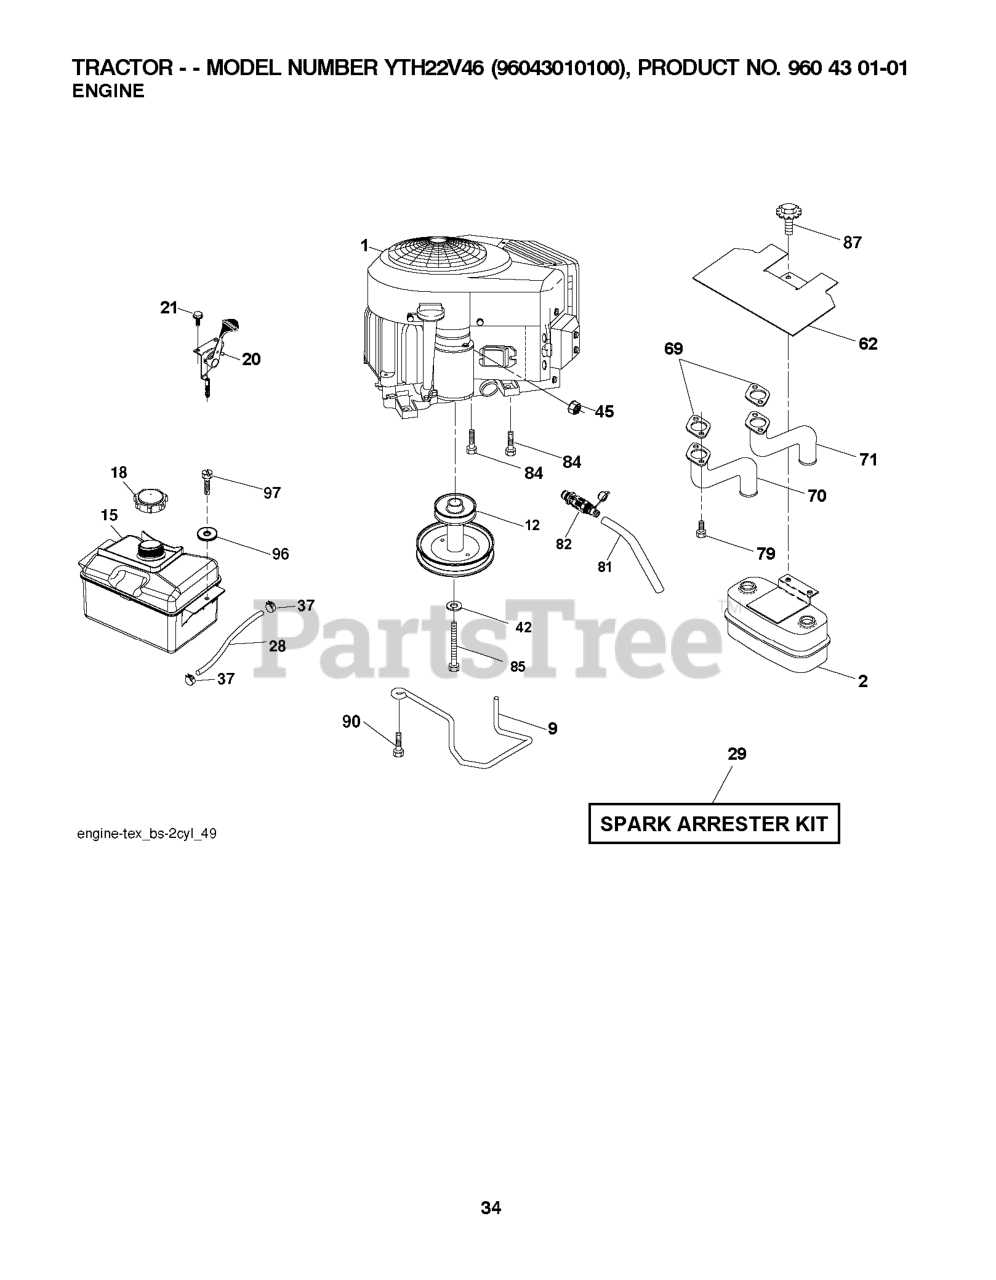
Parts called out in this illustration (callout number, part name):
2	MUFFLER.TWIN.CYL.LOW.TONE
9	KEEPER.BELT.ENGINE.4.2
12	RP_PULLEY ENGINE
15	TANK.ASM.FUEL.FR.2.5GA.
18	CAP ASM.FUEL.2.25"FR.
20	CONTROL.TH/CK.COBRA.B&S.TWN.BK
21	SCREW.#10 X 0.750.BOS
22	CONTROL.CHOKE.ERGO.PUSH-IN.BLA
28	LINE.FUEL.20"FRONT.EMI
29	KIT.SPARK ARRESTOR 794945 B&S
37	HOSE CLAMP
42	LOCKWASHER
45	NUT
62	RP SHIELD HEAT MUFFLER
69	GASKET.MUFFLER
70	RP.EXHAUST.TUBE.LH.BS/TWIN
71	EXHAUST.TUBE.RH.BS/TWIN
79	SCREW.SOCKET.HEAD.5/16-18
81	TUBE, DRAIN OIL ASM.
82	VALUE.OIL.DRAIN
84	SCREW.3/8-16
85	BOLT HEX 7/16-20X4-1/4"
87	BOLT.5/16-18UNCX3/4 W/SEMS.BLK
90	SCREW 3/8-16X1
97	SCREW HEXWSHR 1/4-20X3/4
